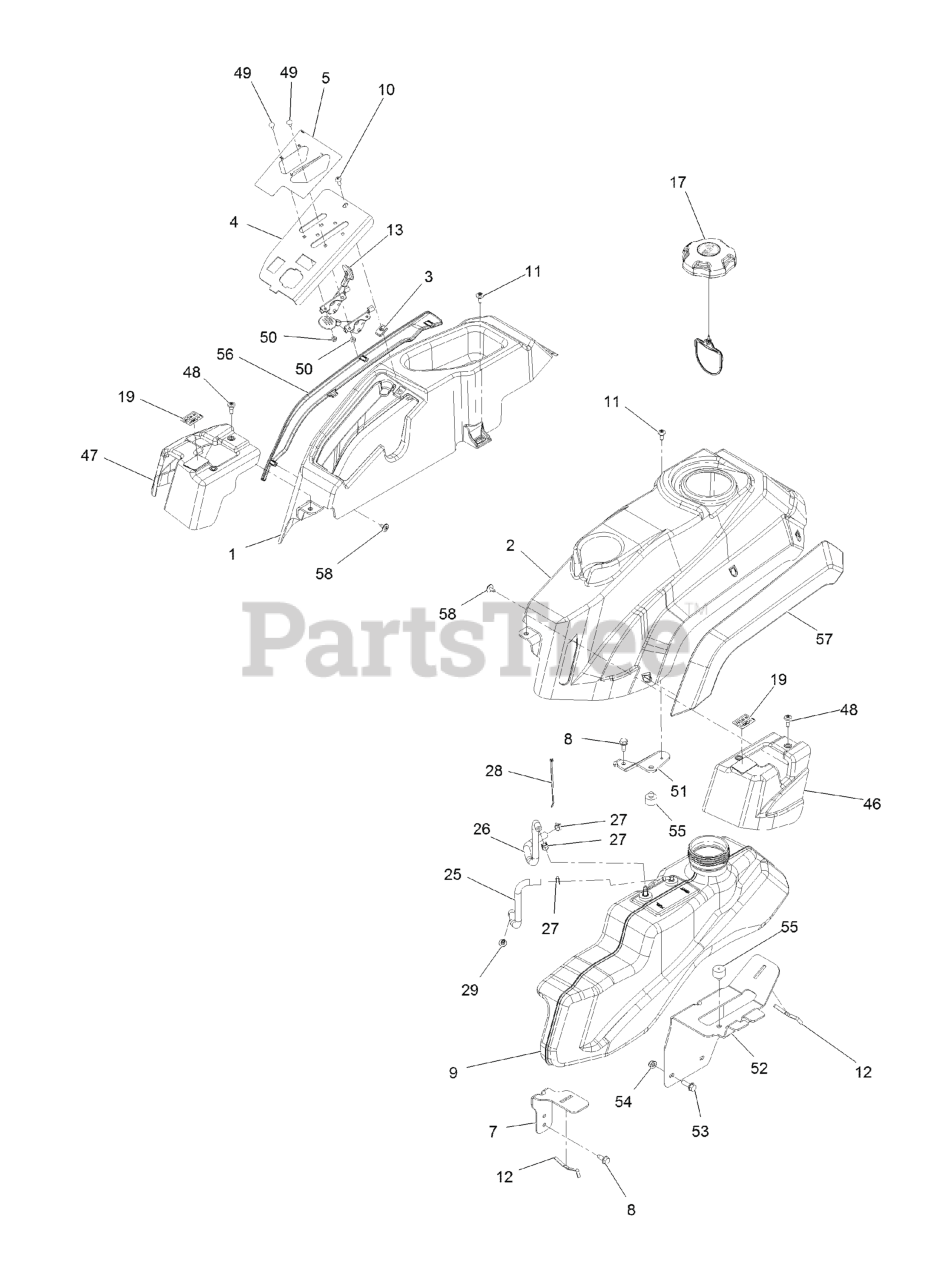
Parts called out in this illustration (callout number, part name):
1	POD-RH, NARROW
2	POD-LH, NARROW
4	PANEL-CONTROL, NARROW
5	DECAL-CONTROL
7	SUPPORT-TANK
8	Screw-HWH 5/16-18 X 3/4 Tf
9	TANK, FUEL
10	SCREW-PRH
11	SCREW-SHOULDER
12	SPRING
13	CABLE-CONTROL, THROTTLE
13	CABLE-CONTROL, CHOKE
17	CAP-FUEL, RATCHETING
19	DECAL-MOTION CONTROL
25	HOSE-FUEL
26	HOSE-FUEL
27	CLAMP-HOSE
28	TIE-CABLE
29	ADAPTOR-ORIFICE
46	Cover, Motion Control LH
47	Cover, Motion Control RH
48	SCREW-SHOULDER
49	BOLT-CARR
50	NUT-LOCK, NI
51	BRACKET-CLAMP
52	BRACKET-SUPPORT TANK
53	SCREW-HHF
54	NUT-HF, NI
55	BUMPER-GROMMET
56	FENDER-RH
57	FENDER-LH
58	SCREW-TORX
